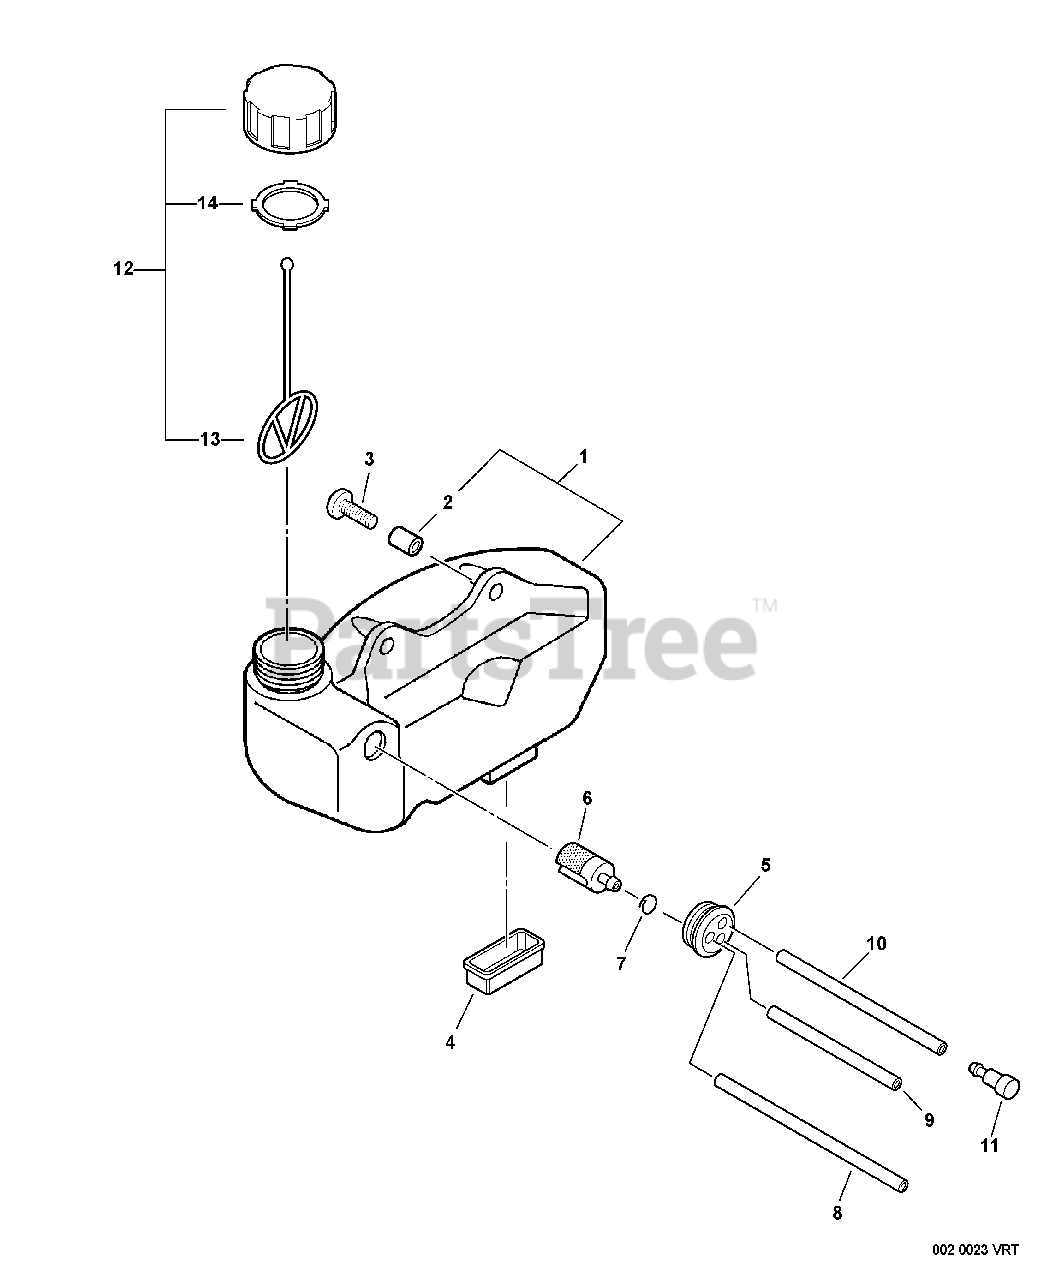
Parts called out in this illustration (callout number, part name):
1	TANK ASSY, FUEL
2	SPACER 6.2×7.8×6
3	SCREW 5×15
4	CUSHION, FUEL TANK
5	GROMMET, FUEL
6	FILTER, FUEL
7	CLIP 6 MM
8	PIPE, FUEL 3×5×195 BLACK
9	PIPE, FUEL RETURN 3×6×110
10	PIPE, FUEL 3x-5x-70 BLACK
11	VENT ASSY
12	CAP ASSY, FUEL
13	CONNECTOR, CAP L= 100 MM
14	GASKET, FUEL CAP
15	TUNE-UP KIT - REPOWER
16	TUNE-UP KIT - REPOWER
17	FUEL SYSTEM KIT
